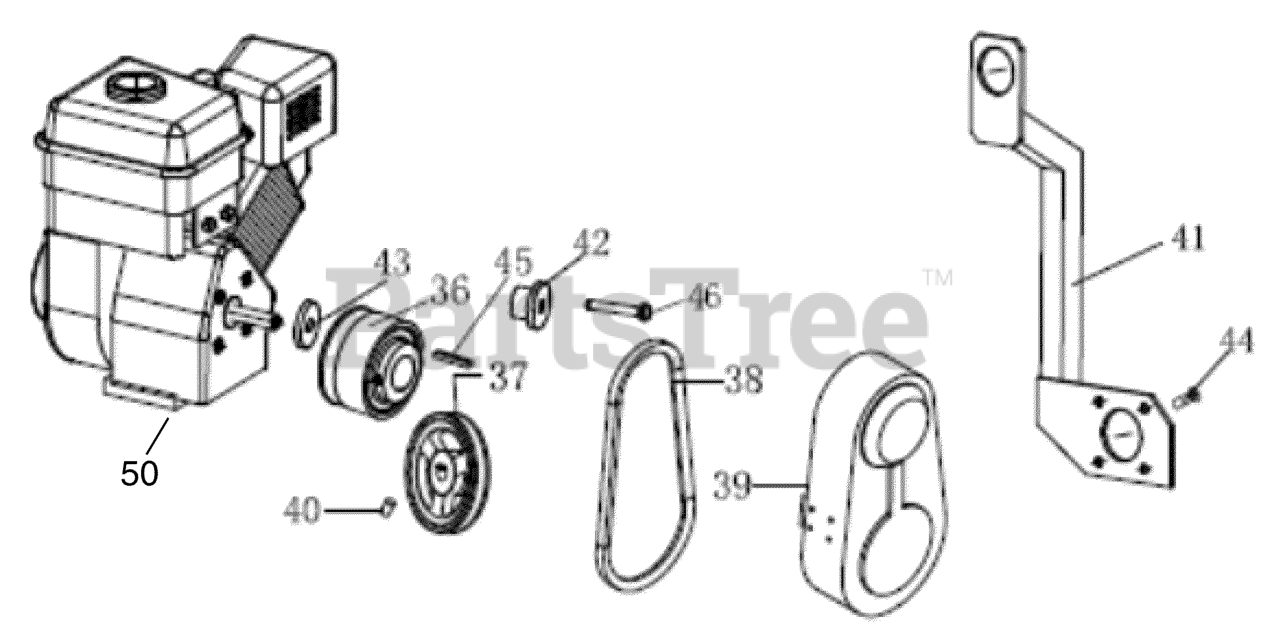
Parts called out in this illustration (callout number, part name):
36	CLUTCH ASSEMBLY
37	PULLEY
39	BELT COVER ASSEMBLY
40	SCREW, Set, M8 x 15
41	LIFTING HOOK
42	LOCATING BUSH
43	WASHER
44	CAPSCREW, Hex Socket, Countersunk Head 5/16-24 x 5/8
50	* ENGINE, Briggs & Stratton
